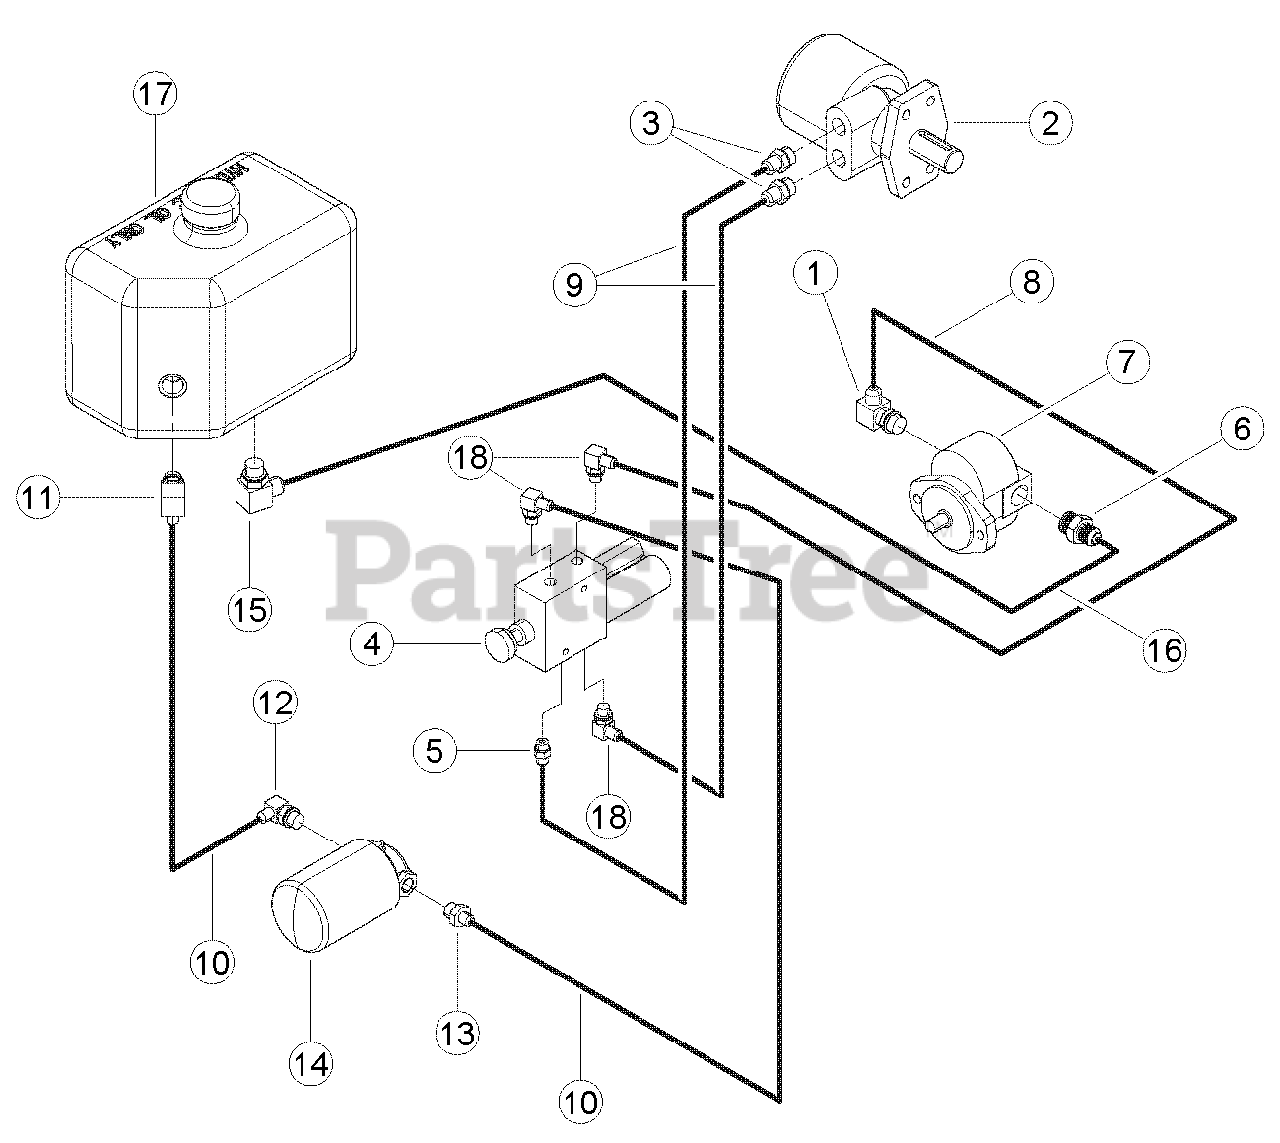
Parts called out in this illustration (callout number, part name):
1	ADAPTER, -10 MORING / -8 MJIC 90 DEG.
2	MOTOR, 32.7 CU IN. HYDRAULIC
3	ADAPTER, -10 MORING / -8 MJIC
4	VALVE, HYDRAULIC CONTROL
5	ADAPTER, -6 MORING / -6 MJIC
6	ADAPTER, -12 MORING / -10 MJIC
7	PUMP, HYDRAULIC FEED
8	HOSE ASSEMBLY, -8 FMJ / -6 FMJ X 38
9	HOSE ASSEMBLY, -8 FMJ / -6 FMJ X 31
10	HOSE ASSEMBLY, -6 FMJ / -6 FMJ X 30
11	ADAPTER, -10 MORING / -6 MJIC 90 DEG.
12	ADAPTER, -8 MORING / -6 MJIC 90 DEG.
13	ADAPTER, -8 MORING / -6 MJIC
14	FILTER, SPIN-ON
15	ADAPTER, -10 MORING / -10 MJIC 90 DEG.
16	HOSE ASSEMBLY, -10 FMJSW 90 / -10 FMJ X 42
17	TANK, HYDRAULIC
18	ADAPTER, -6 MORING / -6 MJIC 90 DEG.
